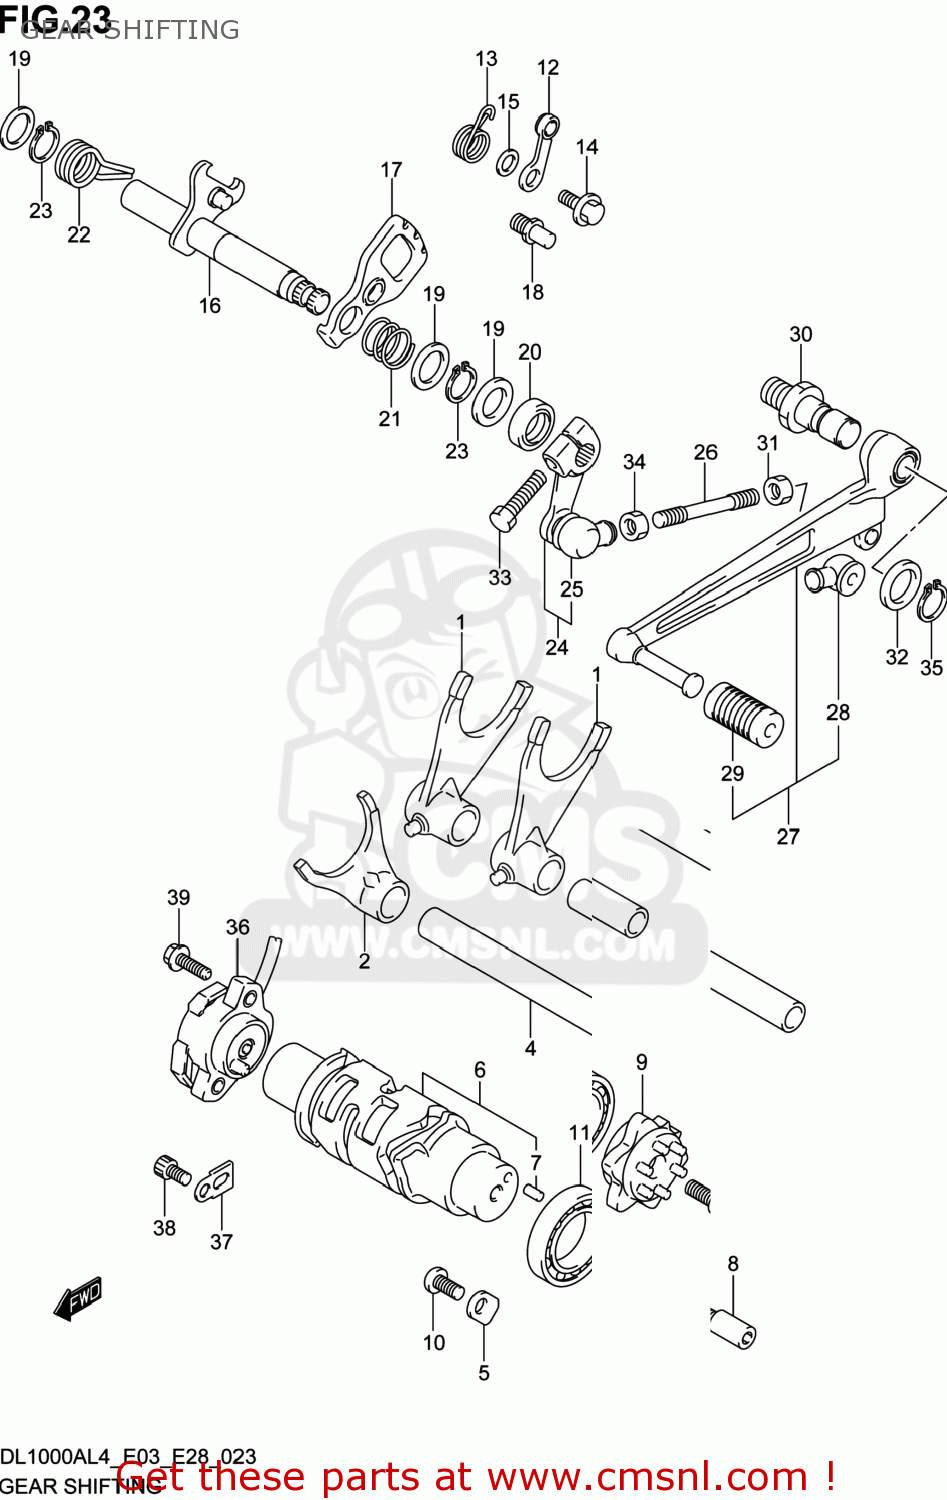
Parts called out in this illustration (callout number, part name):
1	FORK,GEAR SHIFT
2	FORK,GEAR SHIFT NO.3
3	SHAFT,GEAR SHIFT FORK
4	SHAFT,GEAR SHIFT FORK
5	RETAINER
6	CAM,GEAR SHIFT
7	PIN
8	PIN,SHIFT CAM DRIVEN GEAR
9	PLATE,GEAR SHIFT CAM
10	SCREW(6X12)
11	BEARING
12	STOPPER,SHIFT CAM
13	SPRING,GEAR SHIFT CAM STOPPER
14	BOLT(6X14.3)
15	WASHER
16	SHAFT,GEAR SHIFT
17	PLATE,GEAR SHIFT CAM DRIVE
18	STOPPER,GEAR SHIFT ARM
19	SHIM(14X22X1)
20	SEAL,OIL(14X22X7.3)
21	SPRING
22	SPRING
23	CIRCLIP
24	ARM,GEAR SHIFT LINK
25	COVER,DUST
26	ROD,GEAR SHIFT LINK
27	LEVER ASSY,GEAR SHIFT
28	COVER,DUST
29	RUBBER,GEAR SHIFT PEDAL
30	SHAFT,GEAR SHIFT LEVER
31	NUT
32	WASHER(12.5X20X1)
33	BOLT
34	NUT
35	CIRCLIP
36	SENSOR ASSY,GEAR POSITION
37	CLAMP,GENERATOR LEAD WIRE
38	BOLT
39	BOLT(5X16)
